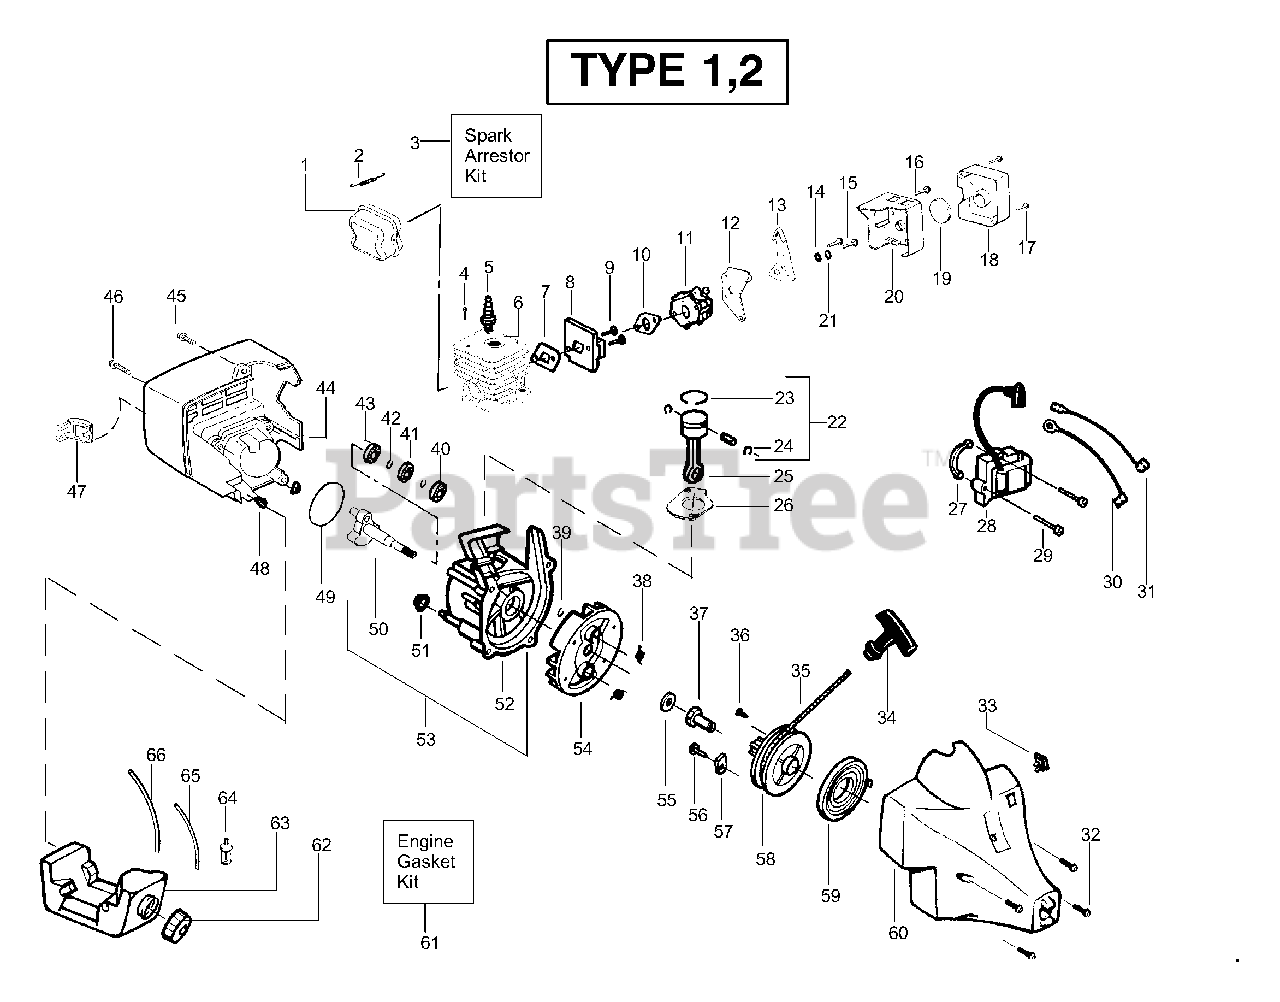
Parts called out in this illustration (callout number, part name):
1	Kit - Muffler
2	Muffler Spring
3	Kit-Spark Arrestor
4	Screw-Cylinder
5	Spark Plug (RCJ 8Y)
6	Kit - Cylinder
7	Gasket-Cyl/Carb.(kit)
8	Kit - Carb. Adaptor
10	Gasket-Carb. (kit)
11	Kit - Carburetor Ass'y
12	Choke Plate Mounting
13	Choke Lever
18	Cover-Air Box
19	Foam-Air Filter
21	Spacer-Choke
22	Kit - Piston
23	Piston Ring
24	Retainer-Piston Pin
25	Assy-Connecting Rod
26	Gasket-Cylinder (kit)
27	Spacer-Module
28	Ignition Module
30	Assy-Ground Wire
31	Assy-Leadwire
32	Screw
33	Kit-Momentary Switch
34	Handle-Starter
35	Kit - Rope
37	Coupling-Drive
38	Spring-Starter Dog
39	Retain. Ring-C'shaft
40	Bearing-Outer
41	Seal-C'case
42	Retainer Ring-C'case
43	Bearing-Inner
46	Screw
47	Guard-Muffler
48	Isolator-Shroud
49	O-Ring-C'case(kit)
50	Assy-Crankshaft
51	Isolator-Crankcase
52	Assy-Crankcase
53	Assy-C'case & C'shaft
54	Assy-Flywheel
55	Washer-Flat
57	Retainer-Can
58	Kit-Starter Pulley
59	Spring-Starter
60	Assy-Fan Housing
61	Kit-Engine Gasket
62	Assy-Fuel Cap
63	Assy-Fuel Tank
64	Assy-Fuel Pickup
65	Kit-Fuel Line
66	Kit-Fuel Line
